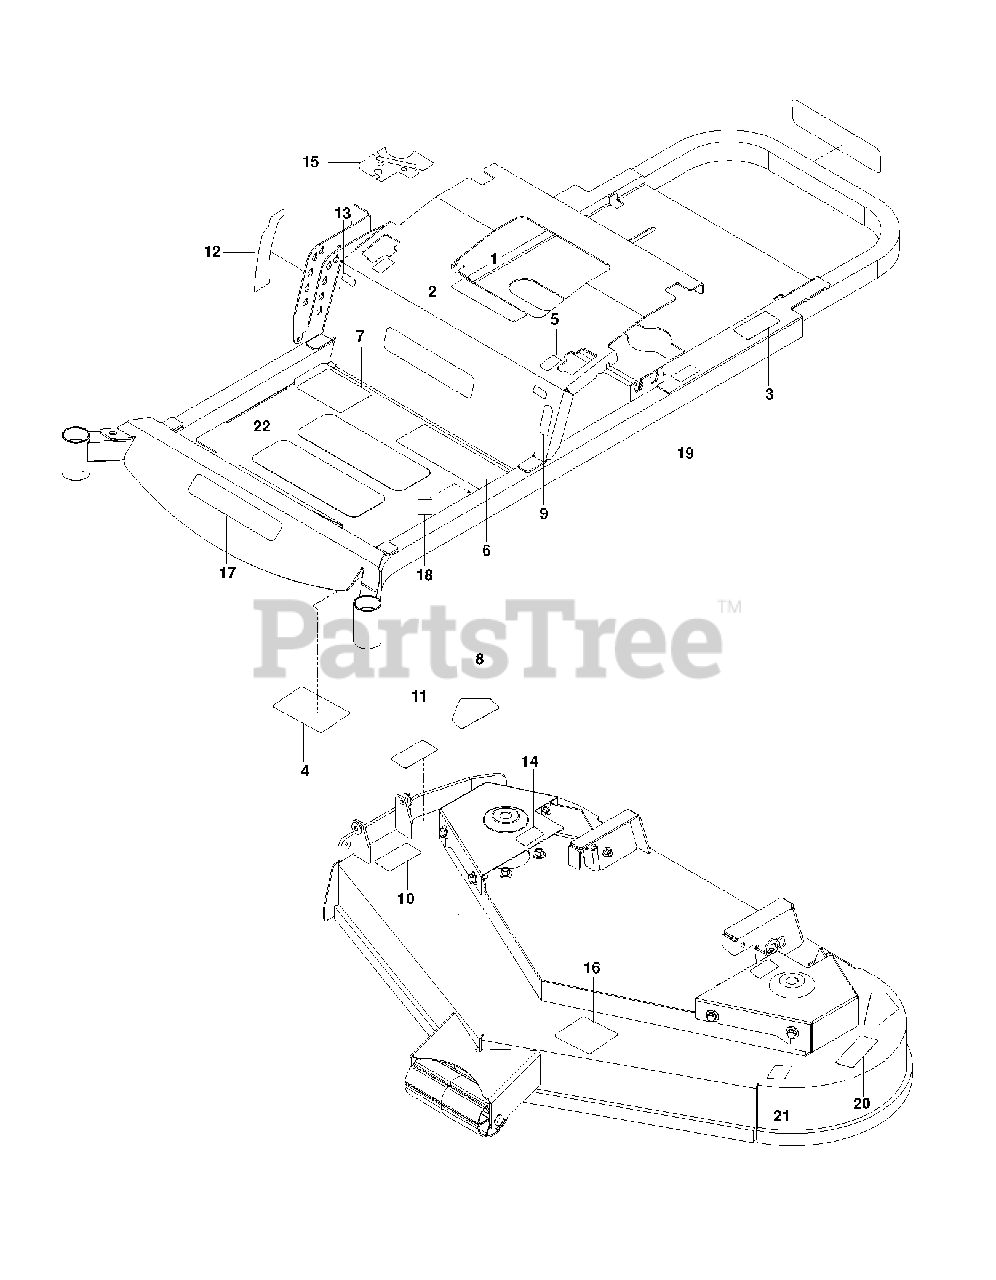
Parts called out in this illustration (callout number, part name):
2	DECAL, SPEEDZTR, 8"
3	DECAL, DO NOT MOUNT
4	DECAL, SERVICE
5	DECAL, MOTION CONTROL
6	DECAL, SAFETY WARNING
7	DECAL, WARNING
8	DECAL, CPSC
9	DECAL, PARK BRAKE
10	DECAL, EURO SEVERING
11	DECAL, DANGER
12	DECAL, HEIGHT
13	DECAL, TRACKING
15	DECAL, CONTROLS PANEL, DIX
16	DECAL, BELT ROUTING
19	DECAL, ECM, AUSTRALIA
20	DECAL, FUSION
21	DECAL, 42
22	ANTI-SKID PAD
